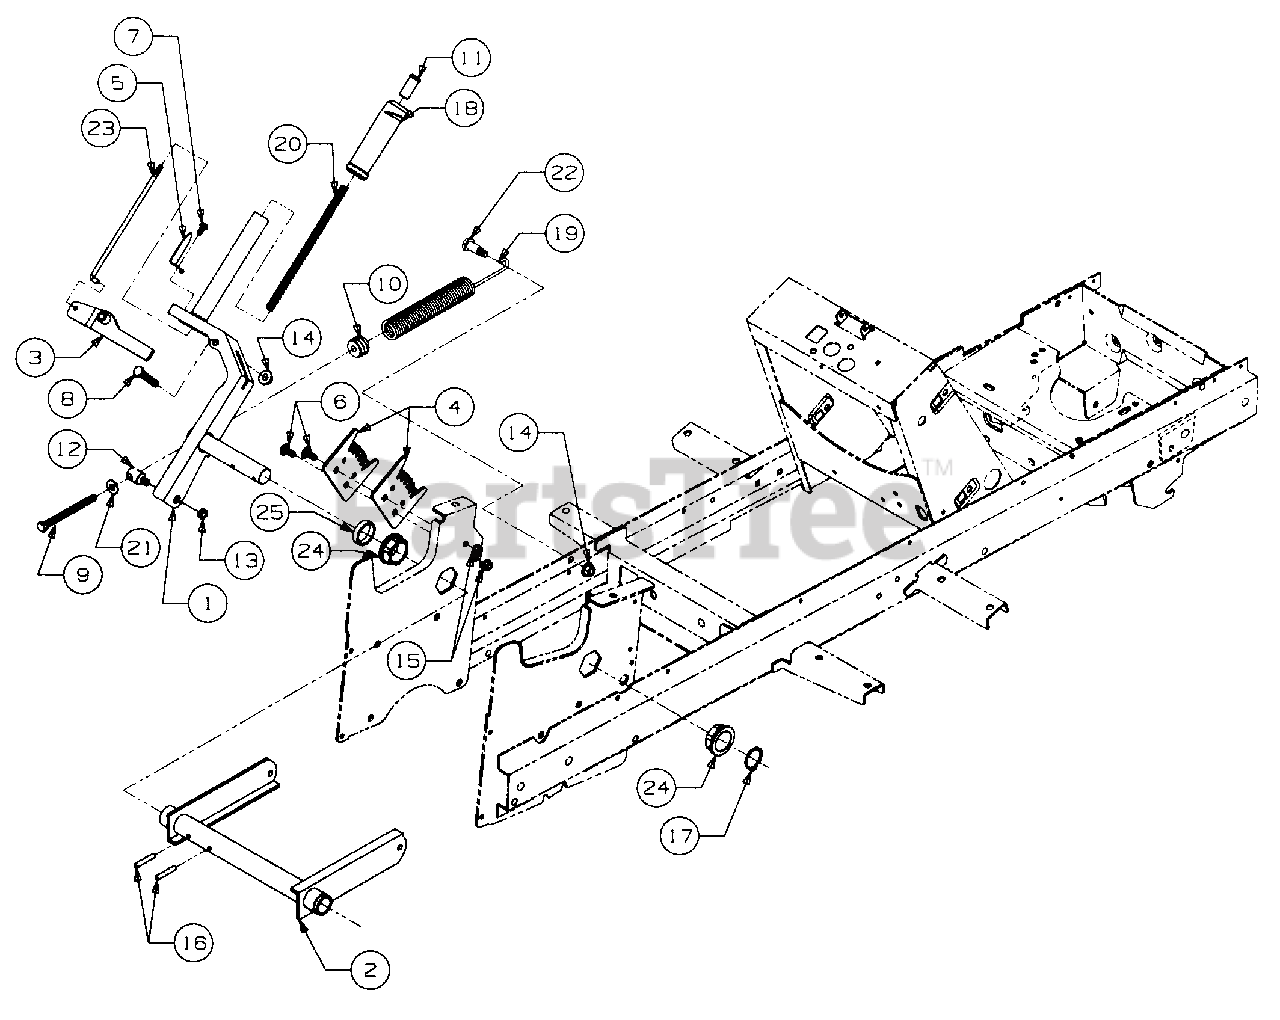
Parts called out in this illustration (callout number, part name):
3	Fork, Lift
4	Bracket, Lift Index
5	Indicator, Lift Height
6	Bolt, Carriage, 5/16-18 x .75 Lg
7	Screw, Hex Wash Tapp, 1/4 x .50 Lg
8	Screw, Hex Cap, 3/8-16 x 2.0 Lg GR5
9	Screw, Hex Cap, 3/8-16 x 4.25 Lg GR5
10	Insert, Spring
11	Button, Handle
12	Ferrule, Adjustment
13	Nut, Hex Center Lock, Jam, 3/8-24
14	Nut, Hex Flanged Lock, 3/8-16
15	Nut, Hex Flanged Top Lock, 5/1 6-18
16	Pin, Spiral Spring, 1/4 Dia x 1.50 Lg
17	Ring, Snap, 1.25 Dia Shaft
18	Grip, Lift Handle
19	Spring, Extension
20	Spring, Compression
21	Washer, Flat, .385 x .87 x .06 Thk
22	Bolt, Shoulder
23	Rod, Index
24	Bearing, Hex Flange, 1.25 ID
25	Spacer, 1.28 ID x 1.5 OD x .335 Lg
